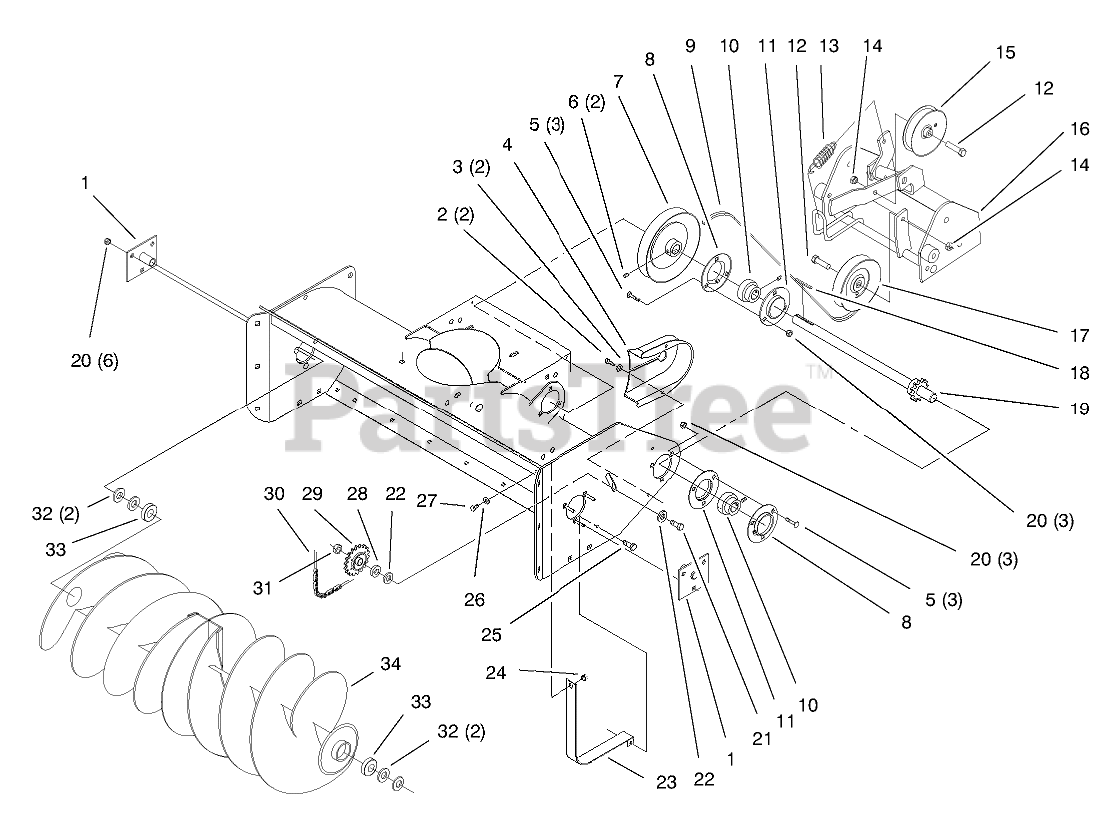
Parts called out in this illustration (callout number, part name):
1	SUPPORT
2	SCREW-HWH
3	WASHER-FLAT
4	GUARD-CHAIN
5	BOLT-CARR
6	SCREW-SQH
7	PULLEY
8	Flange
9	V-BELT
10	BEARING AND COLLAR
11	FLANGE-ZERK RELUBE
12	SCREW-HH
13	SPRING-EXTENSION
14	NUT-LOCK, NI
15	PULLEY-IDLER
16	Pulley Frame ASM
17	PULLEY-IDLER
18	Key
19	Drive Shaft-Welded
20	NUT-LOCK, NI
21	SCREW-HH
22	WASHER-FLAT
23	GUARD-INNER
24	NUT-KEPS
25	SCREW
26	WASHER-FLAT
27	SCREW-HH
28	SPACER
29	Idler Sprocket
30	CHAIN
31	NUT-LOCK, NI
32	WASHER-FLAT
33	BEARING-BALL
34	Auger
